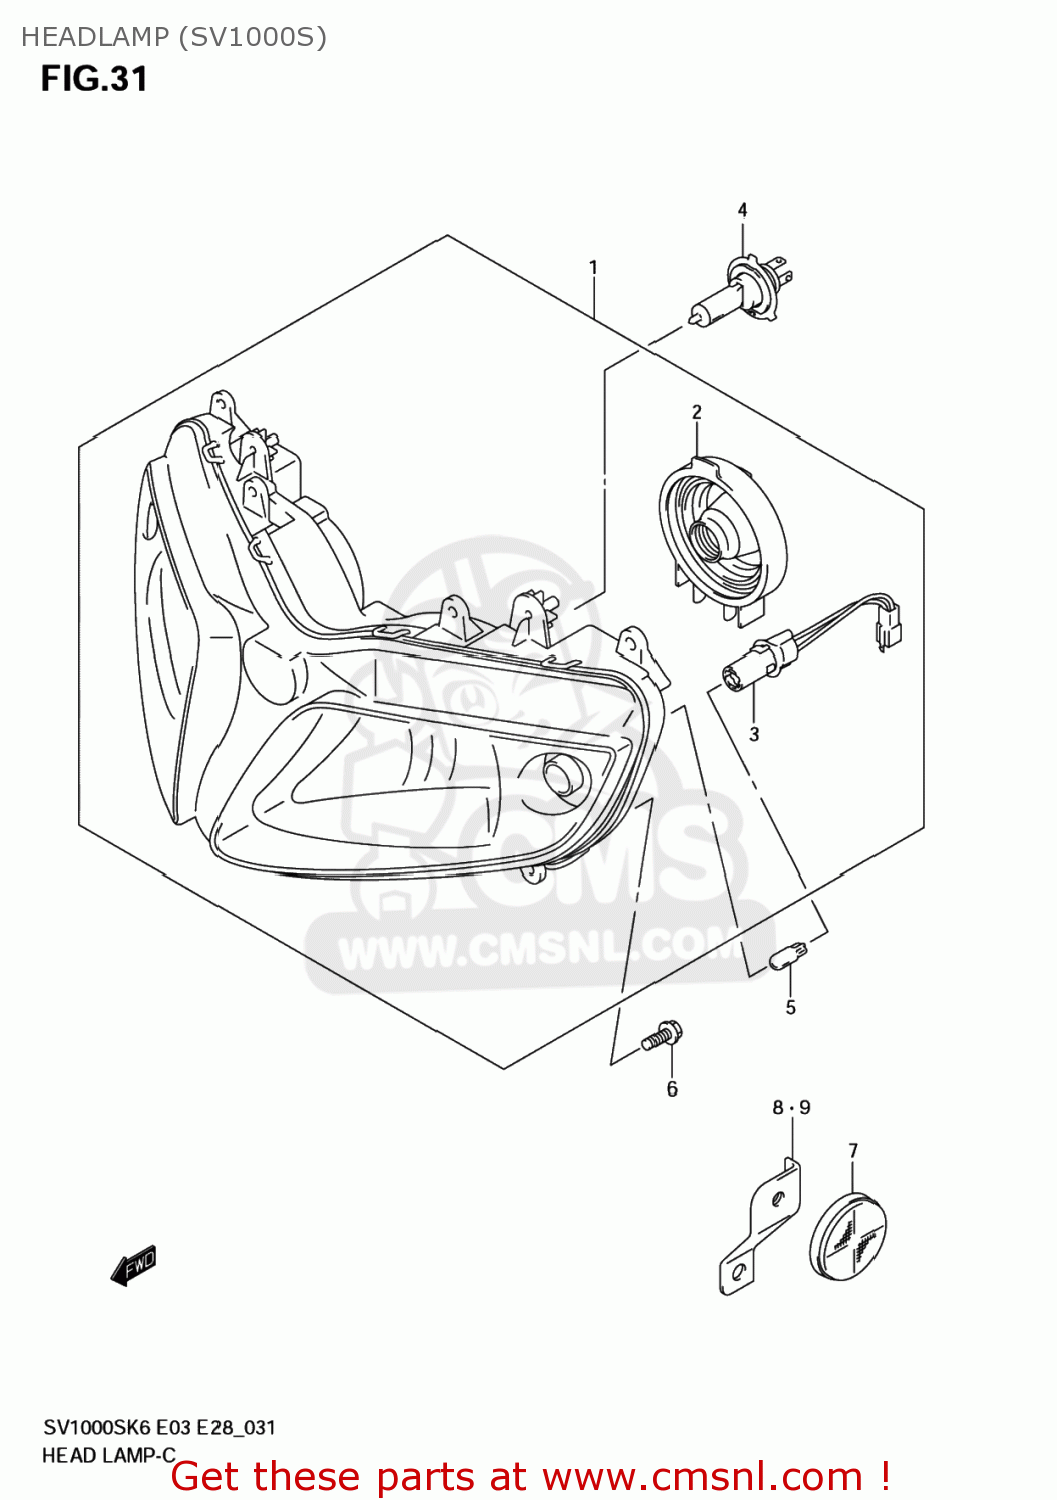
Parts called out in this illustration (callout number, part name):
1	HEADLAMP ASSY
2	COVER,SOCKET
3	CORD ASSY
4	BULB(12V60/55W,H4)
5	BULB(12V5W)
6	SCREW
7	REFLECTOR,REFLEX
8	BRACKET,FR SIDE REFLECTOR,R
9	BRACKET,FR SIDE REFLECTOR,L
